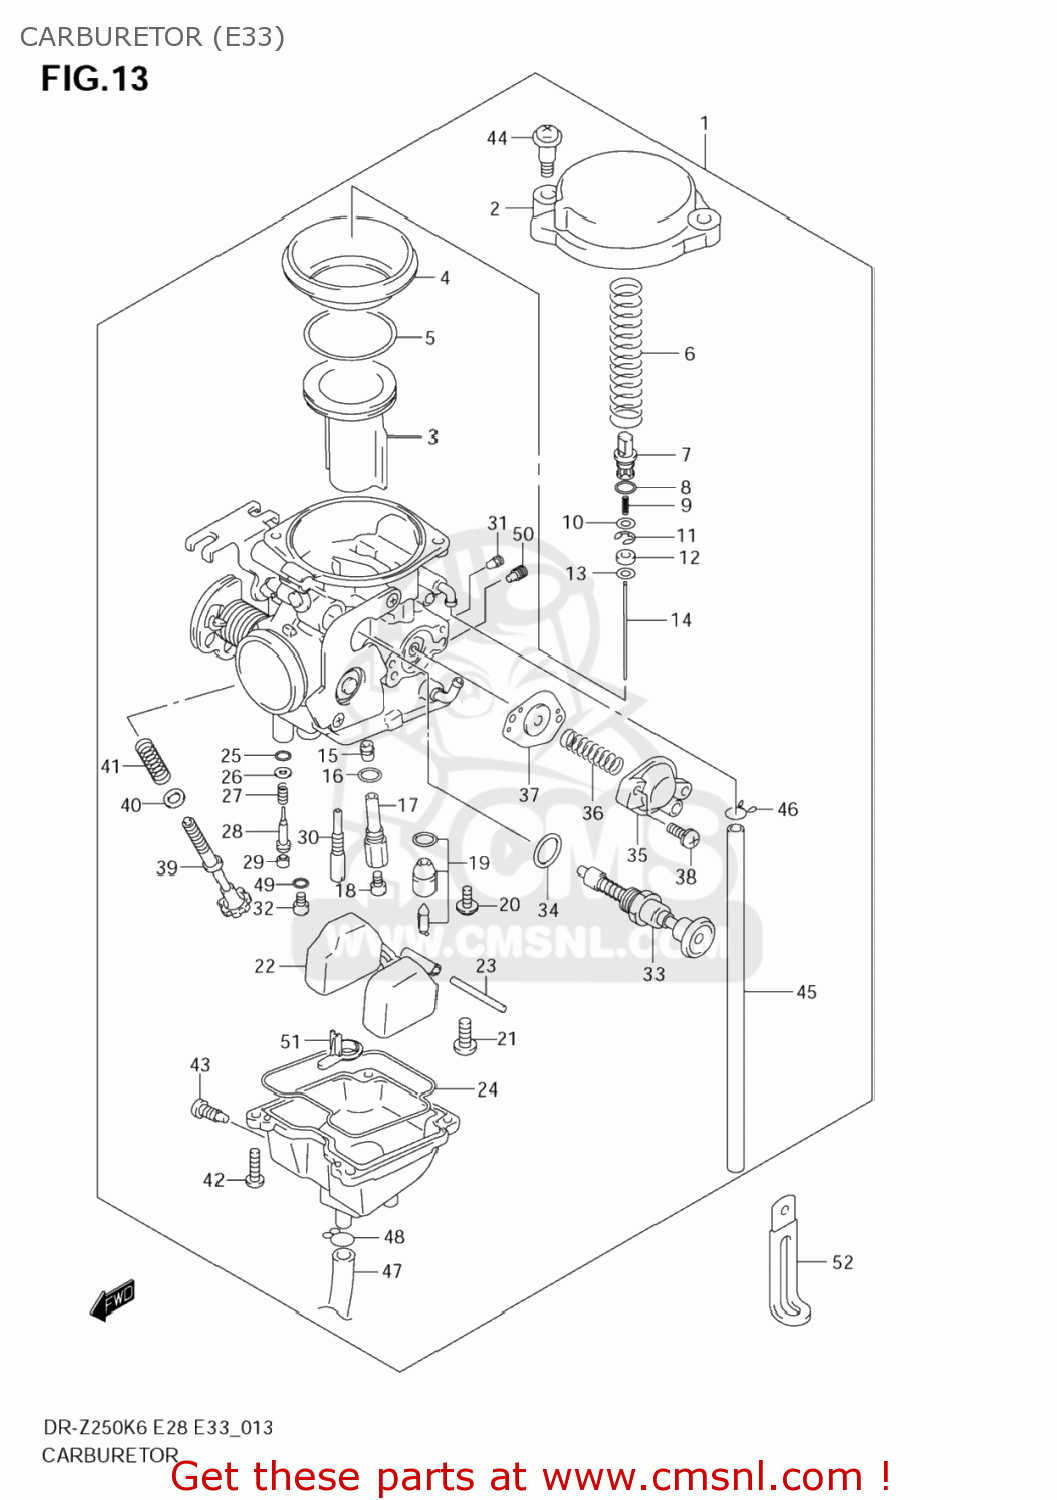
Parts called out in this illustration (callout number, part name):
1	CARBURETOR ASSY
2	COVER,DIAPHRAGM
3	VALVE,PISTON
4	DIAPHRAGM
5	RING
6	SPRING
7	HOLDER
8	O RING(D:1.9,ID:4.8)
9	SPRING
10	WASHER
11	E RING,MULTIPLE JET NOZZLE
12	RING
13	WASHER
14	NEEDLE JET
15	JET
16	O RING
17	HOLDER,JET
18	JET,MAIN (132.5)
19	VALVE ASSY,NEEDLE
20	SCREW
21	SCREW
22	FLOAT ASSY
23	PIN,FLOAT
24	GASKET (NAS)
25	O RING,PILOT AIR SCREW
26	WASHER
27	SPRING,THROTTLE SCREW
28	ADJUSTER
29	PLUG
30	JET,PILOT(12.5)
31	JET(80)
32	JET,MAIN(55)
33	PLUNGER ASSY
34	O RING
35	COVER ASSY
36	SPRING
37	DIAPHRAGM ASSY
38	SCREW
39	ADJUSTER
40	PACKING (NAS)
41	SPRING
42	SCREW
43	SCREW,DRAIN
44	SCREW
45	HOSE
46	CLIP
47	HOSE(4.5X8X650)
48	CLIP
49	O RING
50	JET,POWER(150)
51	RING
52	CLAMP(L:45)
